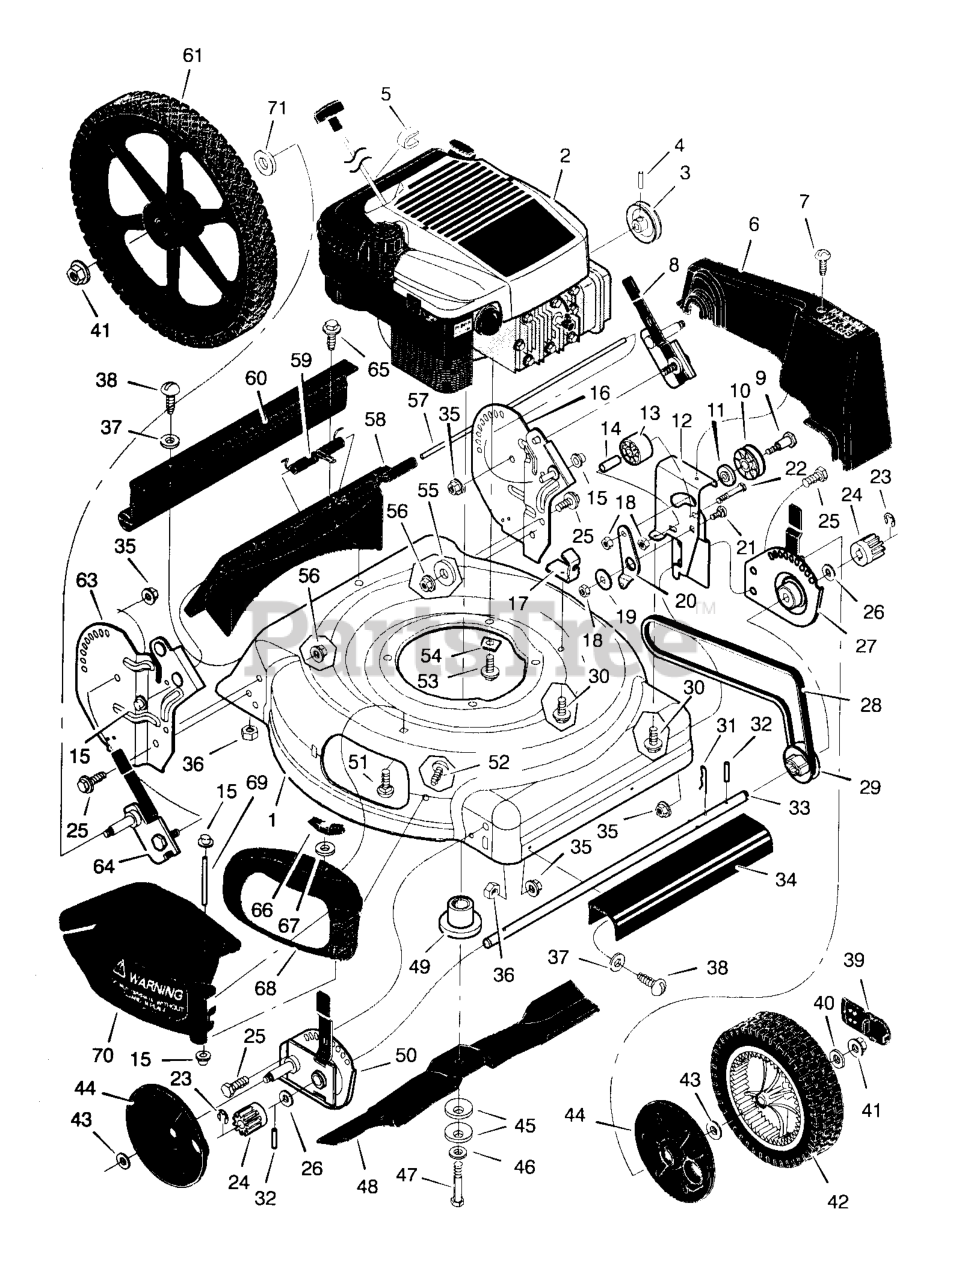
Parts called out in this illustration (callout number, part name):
1	Housing
2	Engine *
3	Pulley, Engine
4	Pin, Spring
5	Stop, Rope (Recoil - Start)
6	Cover, Belt
8	Adjuster, Left Height
9	Bolt, Shoulder
12	Bracket, Idler Support
13	Pulley, Idler
14	Bearing
15	Push On Cap
16	Bracket, Left Handle
17	Bracket, Cable
18	Nut, Hex
20	Arm, Idler
21	Bolt, Carriage
22	Bolt, Shoulder
23	E- Ring
24	Gear, Pinion
25	Bolt
27	Adjuster, Left Front Height
29	Pulley, Axle
31	Pin, Hair
32	Pin, Spring
34	Cover, Axle
35	Nut, Flange
36	Nut, Hex
39	Hub Cap
40	Washer
41	Nut, Flange
42	Wheel, Drive *
44	Cover, Dust
45	Washer, Belleville
49	Adapter, Blade
50	Adjuster, Right Front Height
51	Bolt, Carriage
53	Bolt, Engine
54	Support, Engine
55	Washer
56	Nut, Flange
57	Rod, Pivot
58	Door, Rear
60	Guard, Rear
61	Wheel, Rear *
62	Nut, Flange
63	Bracket, Right Handle
64	Adjuster, Right Height
66	Wingnut
67	Retainer, Push
69	Pin, Pivot
70	Deflector, Chute
